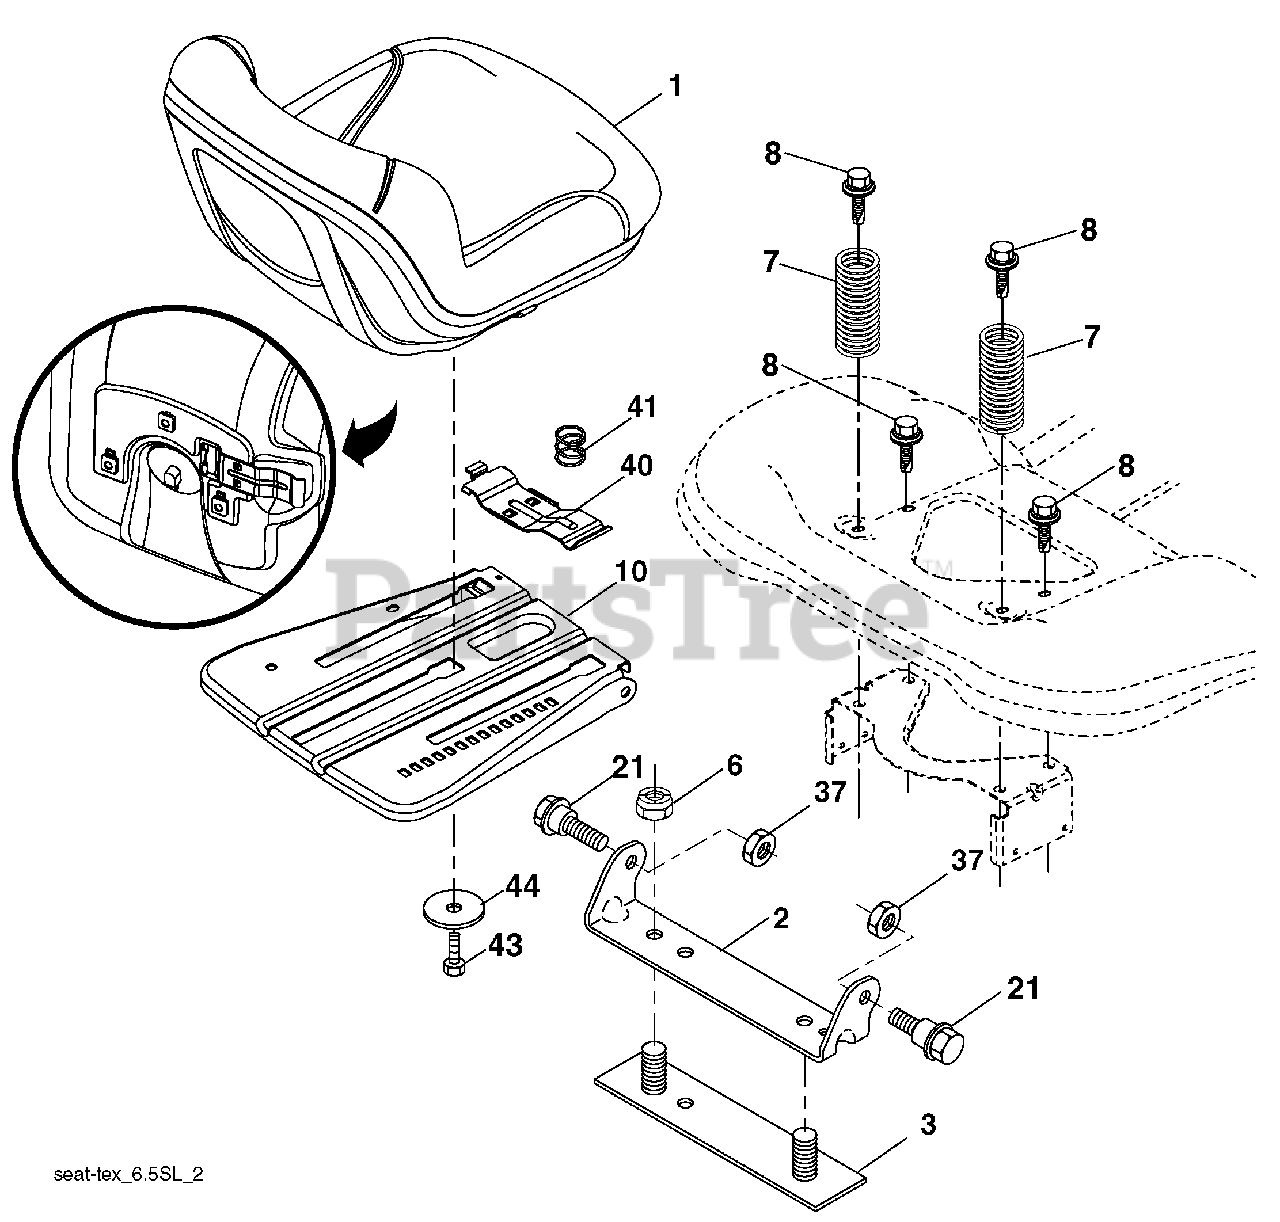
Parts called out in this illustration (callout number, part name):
1	Seat
2	Bracket Pivot Fender
3	Strap, Asm Fender
6	Nut, Lock w/Ins. 3/8-16 unc
7	Spring, Seat Cprsn
8	Bolt 5/16-18 unc x 3/4 w/Sems
10	Pan, Seat
21	Bolt, Shoulder 5/16-18
37	Nut, Lock 5/16-18 unc
40	Handle Slide
41	Spring Latch
43	Bolt 3/8-16 unc x 3/4
44	Washer 13/32 x 2 3/8 x 12 Ga.
